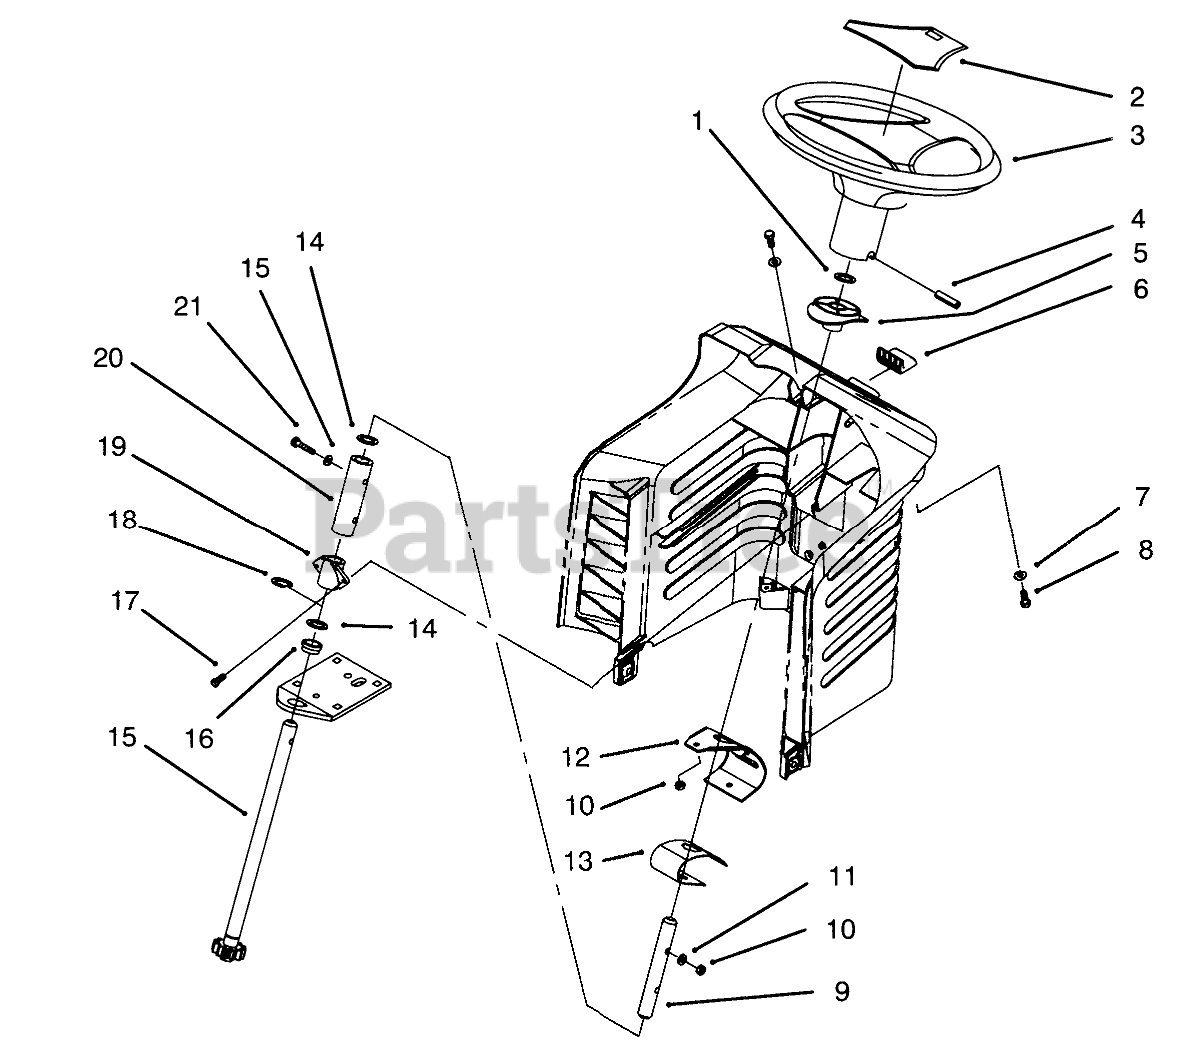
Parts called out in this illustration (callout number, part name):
1	PUSH-ON RETAINING RING
2	COVER-WHEEL
3	Wheel-Steering (Incl. Ref. #2)
4	PIN-ROLL
5	BUSHING-SLIDING
6	Button-Release
7	WASHER-FLAT
8	SCREW-HH
9	UPPER STEERING SHAFT
10	NUT-LOCK, NI
11	WASHER
12	BACKUP BRACKET
13	SPRING LEAF
14	WASHER-THRUST
15	SHORT STRG SHAFT WA
16	BEARING-FLANGE
17	SCREW-SPECIAL
18	E-RING
19	BUSHING STATIONARY
20	COUPLING, STEERING
21	SCREW-HH
